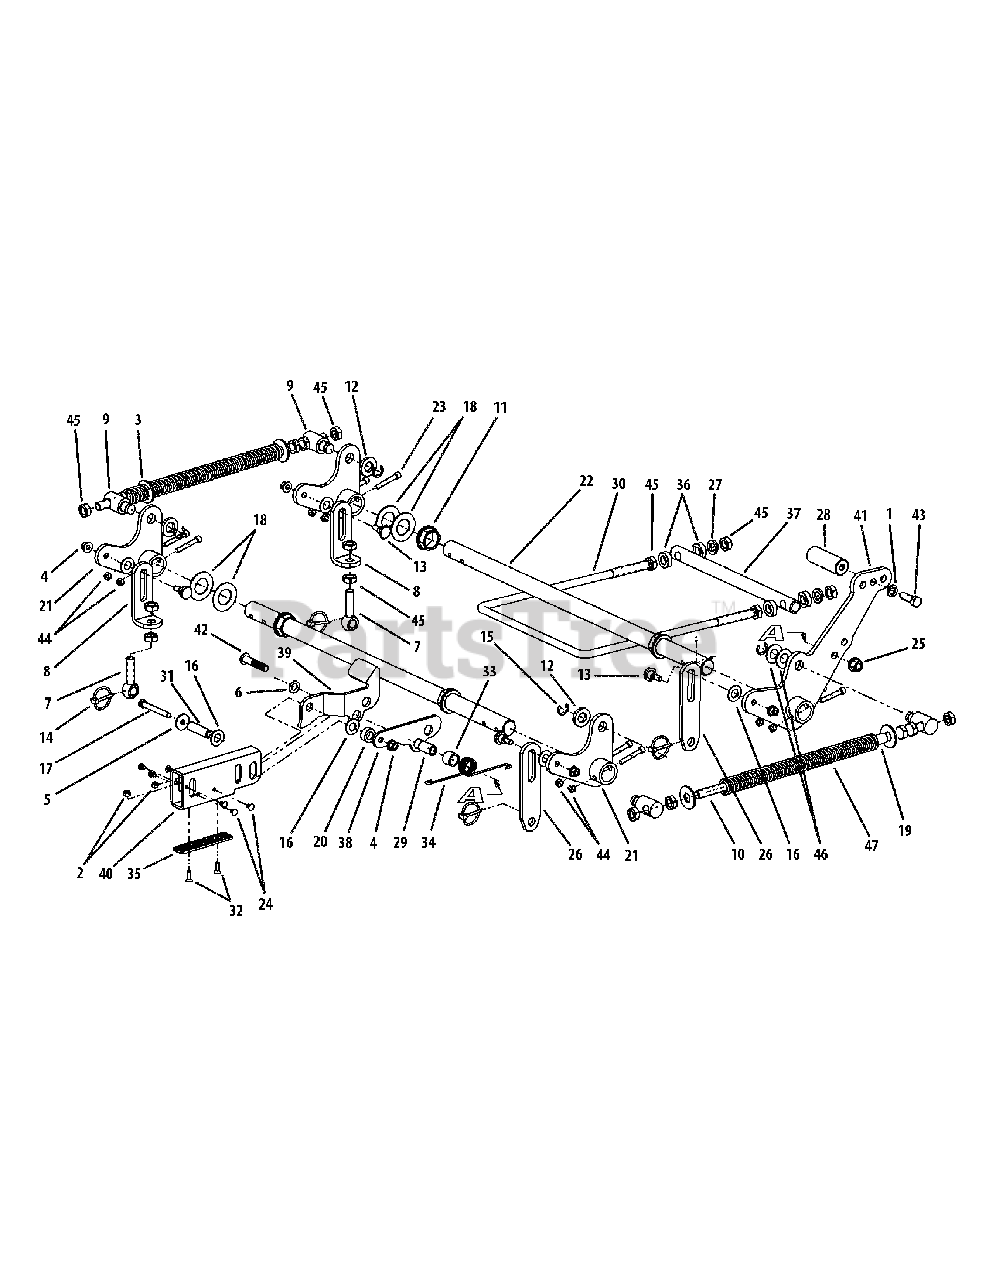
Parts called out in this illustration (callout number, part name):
1	Lock Washer, 1/2
2	Lock Nut w/Nylon Insert
3	Flat Washer, 5/8
4	Hex Nut, Flange Lock, 3/8-16
5	Flat Washer, 1.25 x .411 x .100
6	Flat Washer, .536 ID x .930 OD x .05
7	Eye Bolt, 5/8ID
8	Eye Bolt Mount Link, 5/8 ID
9	Ferule Lift
10	Lift Connector Rod
11	Hex Flange Bearing, 1.25 ID
12	Spacer, .812 ID x .268 Lg.
13	Shoulder Screw, 0.625 OD x .437 Lg.
14	Linch Pin, 3/16 Dia.
15	E Clip, 3/4 Dia.
16	Nylon Flat Washer, 5/8
17	HHCS, 3/8-16, 3.00
18	Flat Washer, 1.25 ID
19	Hose, 5/8 ID 13/16 OD, 8" LG
20	Spacer, .630 ID x 1.06 OD x .440
21	Bellecrank Weldment Assembly
22	Deck Lift Shaft
23	Socket Head Cap Screw, 5/16-18 x 2
24	Rivet, 1/4 x 5/8
25	Nut, 1/2-13, Flange Lock
27	Lock Washer, 5/8
28	Deck Lift Foot Pedal
29	Spacer, .51 ID x .75 OD x 1.240
30	Front Lift Rod
31	Spacer, .375 ID x .625 OD x 2.20
32	Flat Head Cap Screw, 1/4-20 x .75
33	Spacer, .76 ID x 1.0 OD x .75
34	Torsion Spring, .120 Wire x 1.32 OD
35	Lift Wear Plate
36	Spacer, .635 x 1.2 x .41
37	Pivot Rod
39	Lift Link Bracket
40	Lift Tube, 3.0 x 1.5
41	Deck Lift Foot Pedal Weldment
42	Cap Screw, 1/2-13 x 2.50
43	Hex Cap Screw, 1/2-13 x 1.50
44	Nut, 5/16-18, Nylock
45	Jam Nut, 5/8-11
46	Flat Washer, .76 x 1.49 x .06
47	Lift Compression Spring (48")
47	Lift Compression Spring (60")
